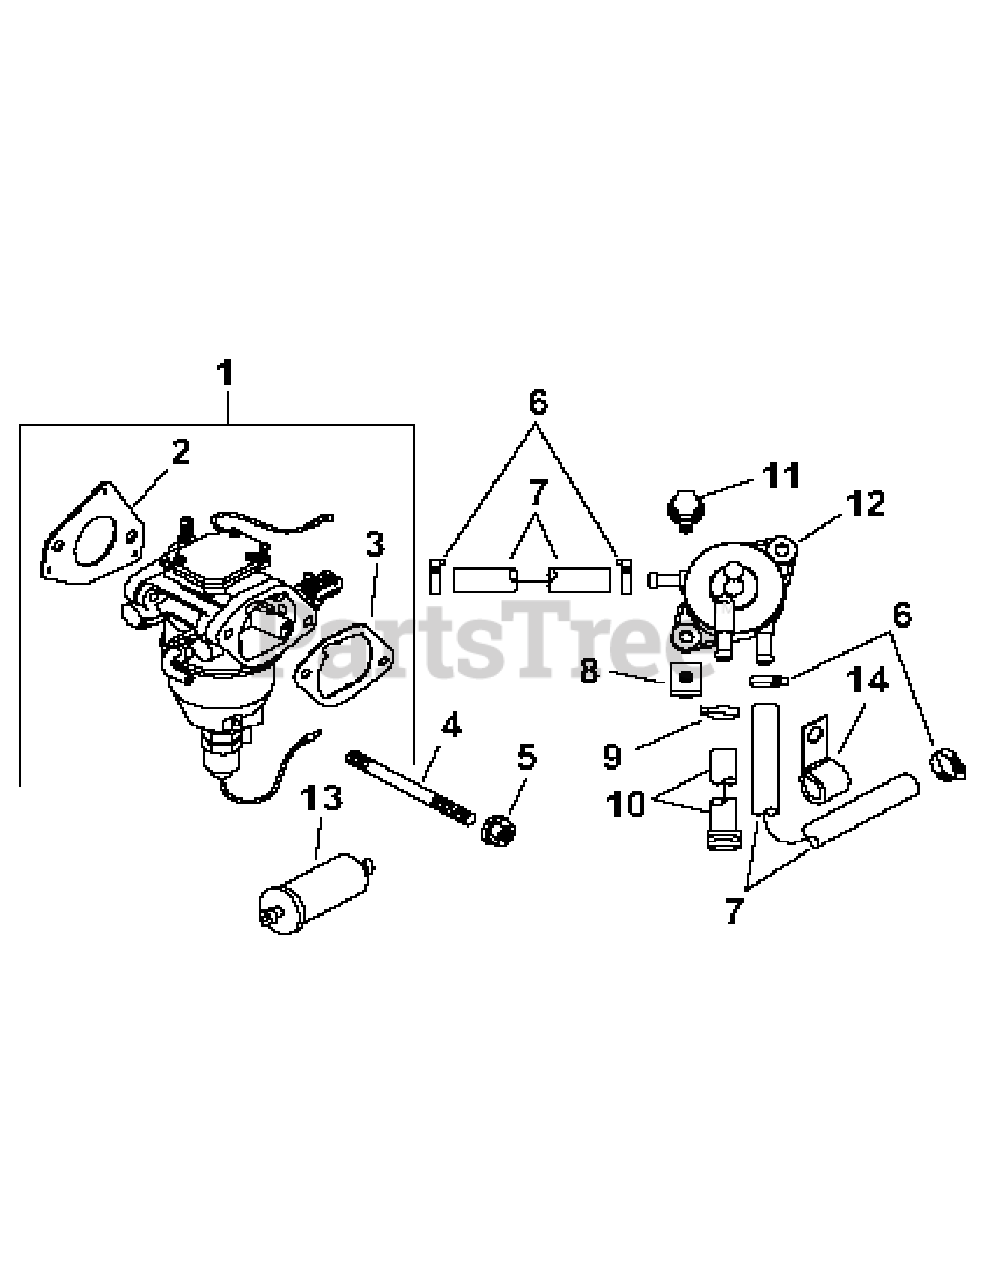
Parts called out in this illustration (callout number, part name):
1	Carburetor Kit w/Gaskets
2	Carburetor Gaskets
3	Air Cleaner Base Gasket
4	Carburetor Stud
5	Hex Flange Nut
6	Hose Clamp
7	Fuel Line
8	Plastic Nut
10	Fuel Pump Hose
11	Hex Cap Screw
12	Pulse Fuel Pump
13	Fuel Filter
